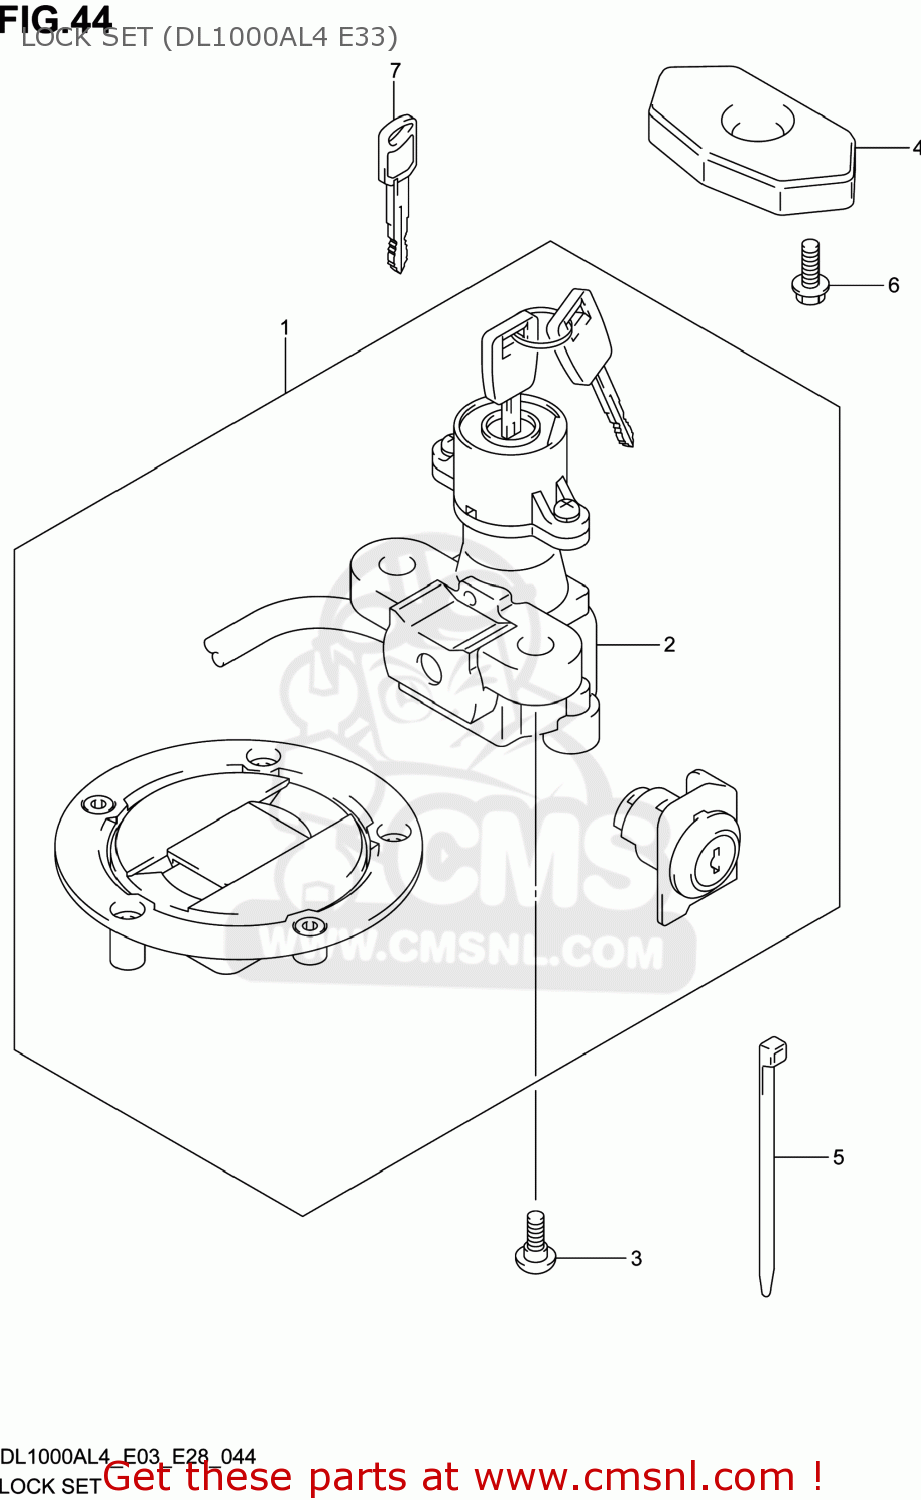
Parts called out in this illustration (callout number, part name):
1	LOCK SET
2	LOCK ASSY,STEERING
3	BOLT(8X20)
4	COVER,STEERING LOCK
5	CLAMP(L:145)
6	BOLT
7	KEY,BLANK
